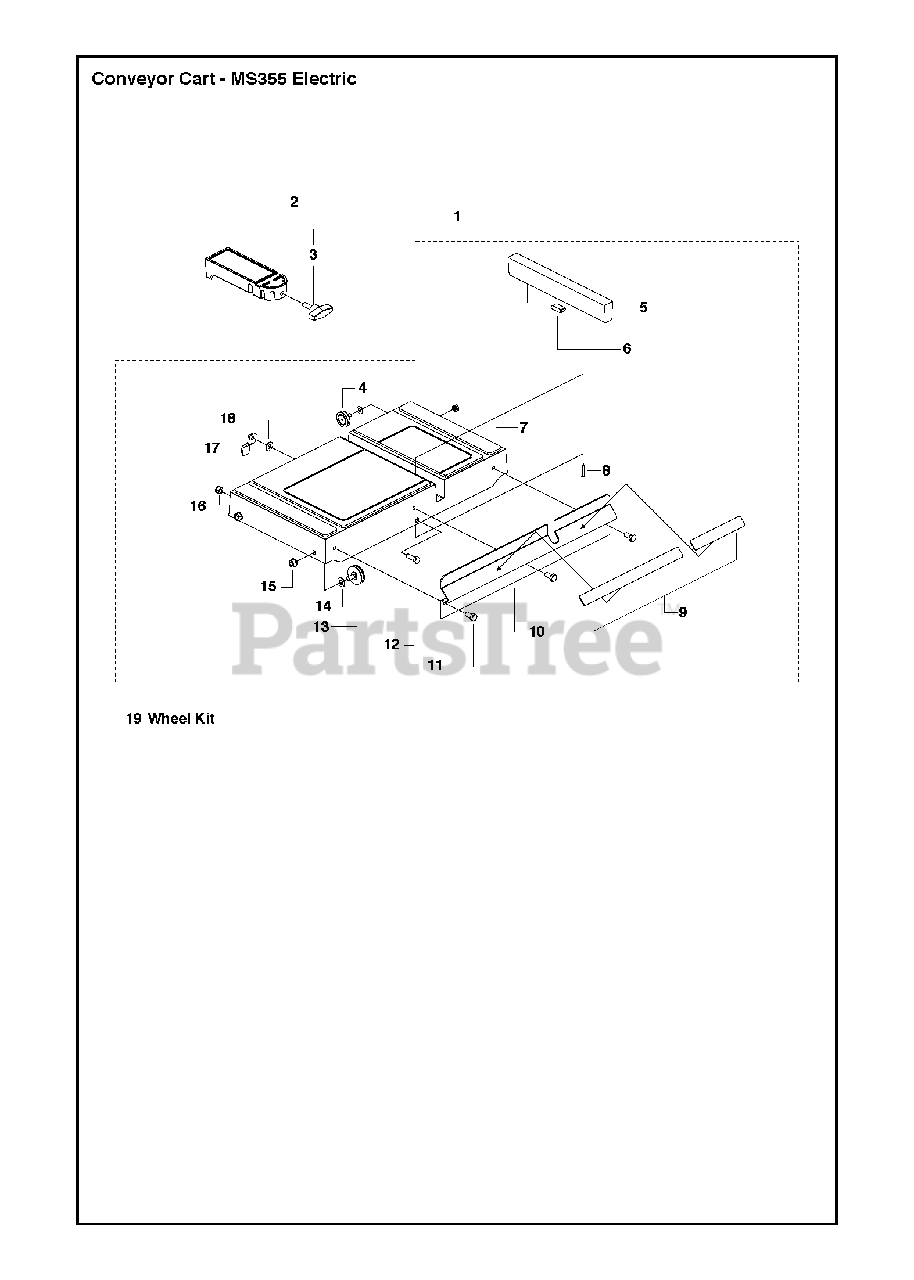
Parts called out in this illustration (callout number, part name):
4	FS700/2/900/2 WHEEL SUR/BEARIN
12	SCREW
14	WASHER
16	NUT
